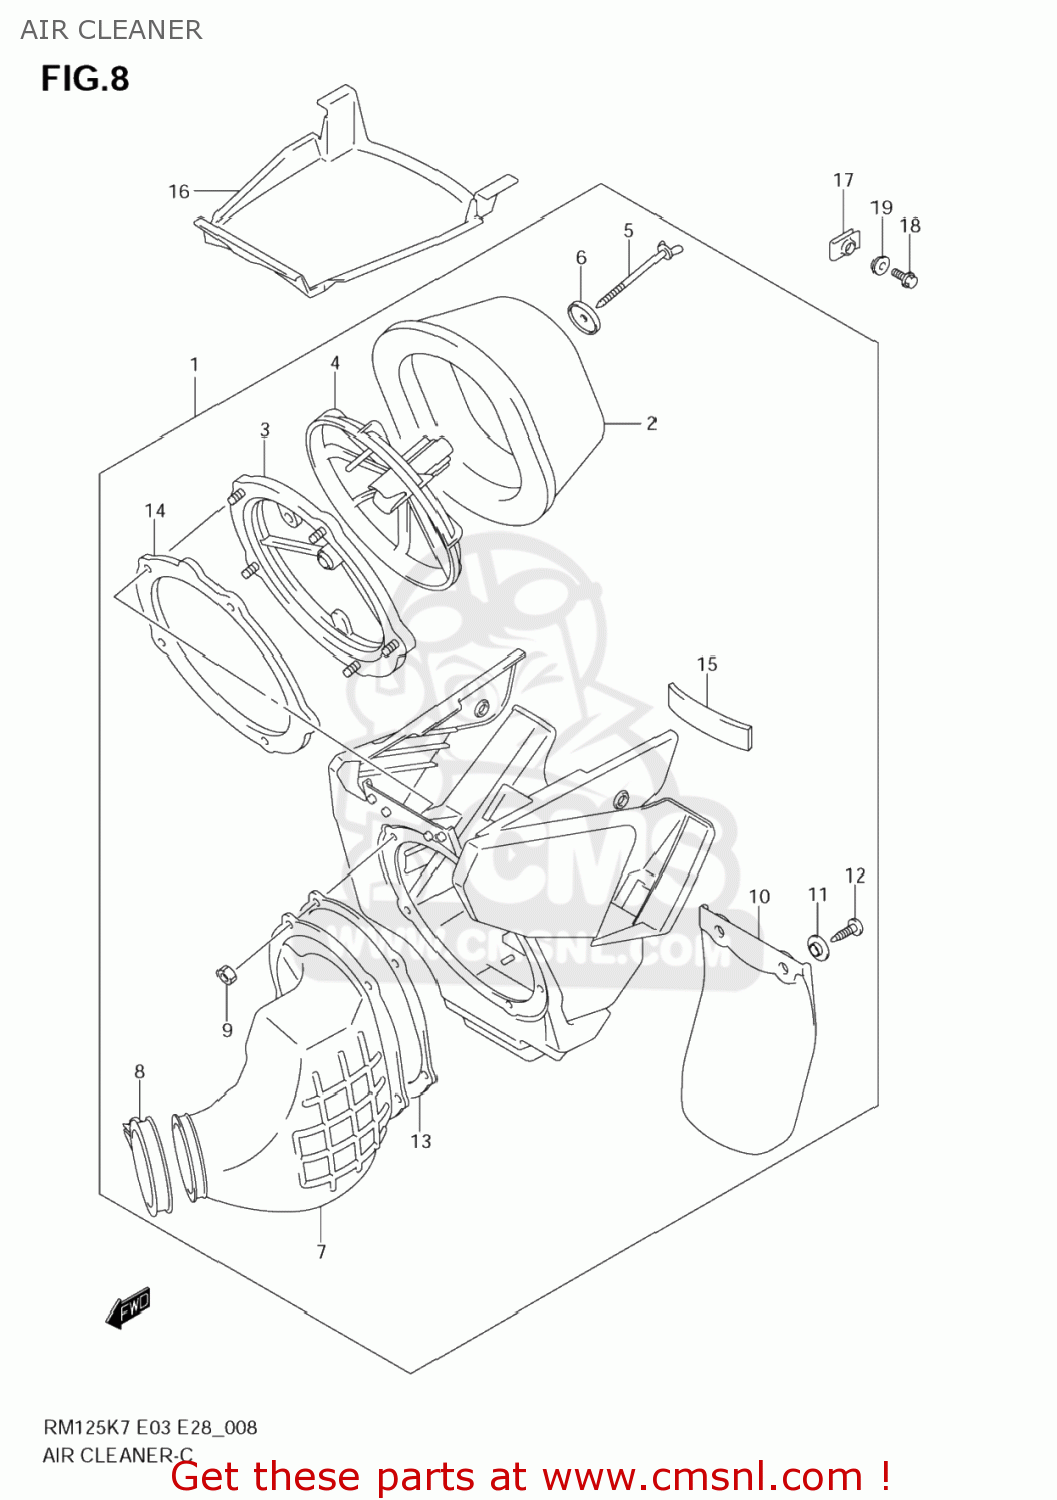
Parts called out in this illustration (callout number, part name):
1	CLEANER ASSY,AIR
2	FILTER ASSY
3	BASE,FILTER
4	HOLDER,FILTER
5	BOLT,WING
6	WASHER,AIR CLEANER
7	TUBE,OUTLET
8	CLAMP
9	NUT
10	MUDGUARD
11	COLLAR
12	SCREW
13	PLATE
14	GASKET (NAS)
15	CUSHION,AIR CLEANER
16	CAP,AIR CLEANER
17	NUT
18	BOLT(6X10)
19	WASHER
